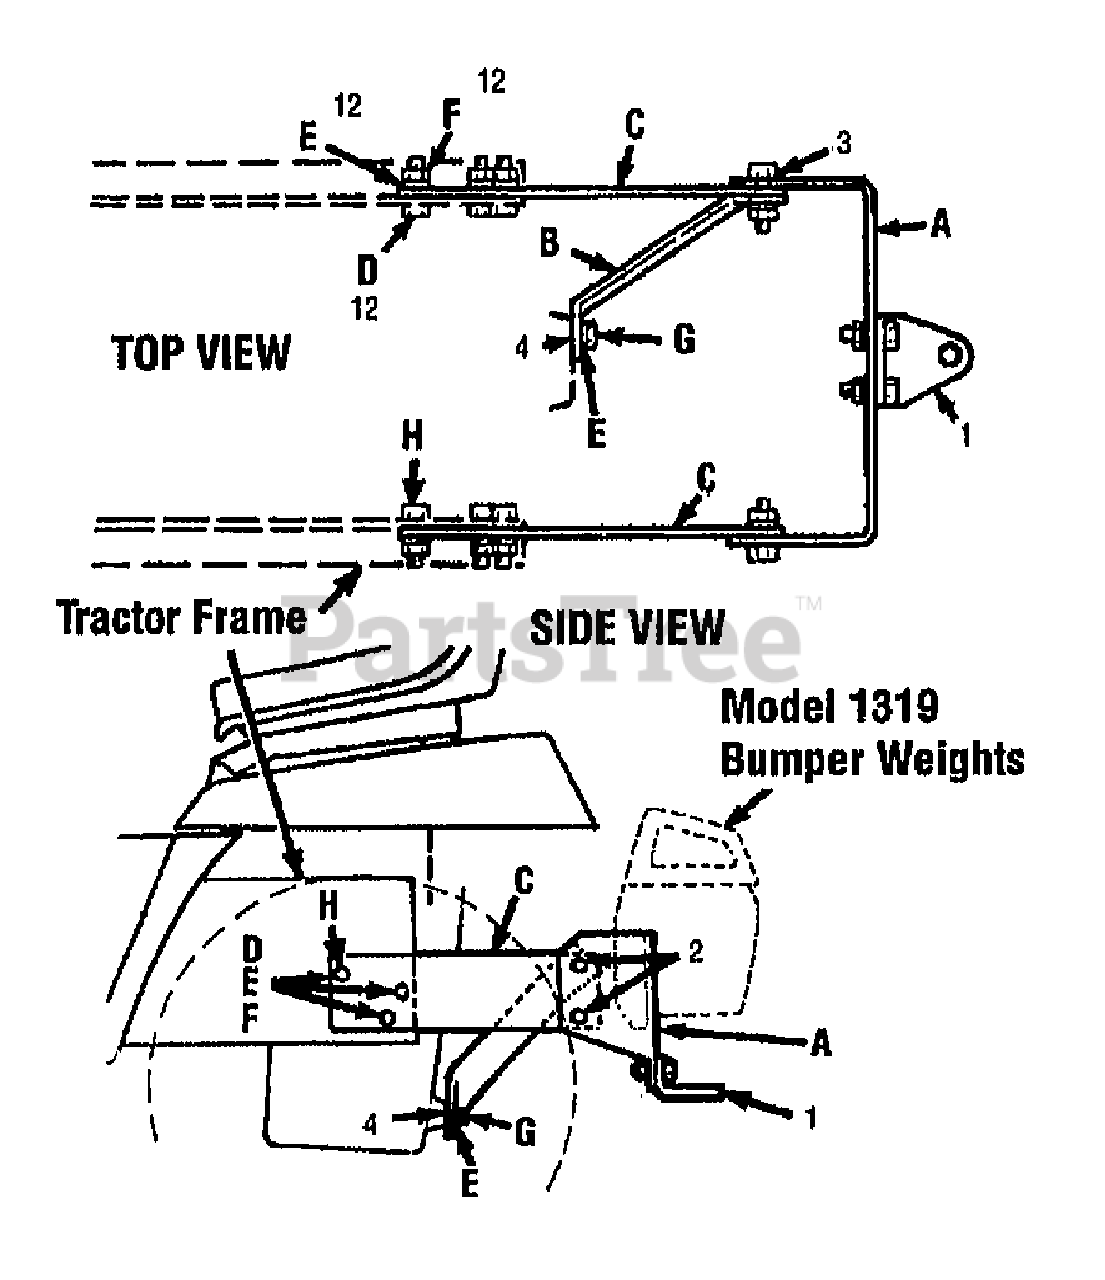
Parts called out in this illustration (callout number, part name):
D	SCR-HH 1/2-13X1.5 G5 ZP
E	WASHER-LK .5
F	NUT-HEX JAM 1/2-13
G	SCR-HH 1/2-13X1.0 G5 ZP
